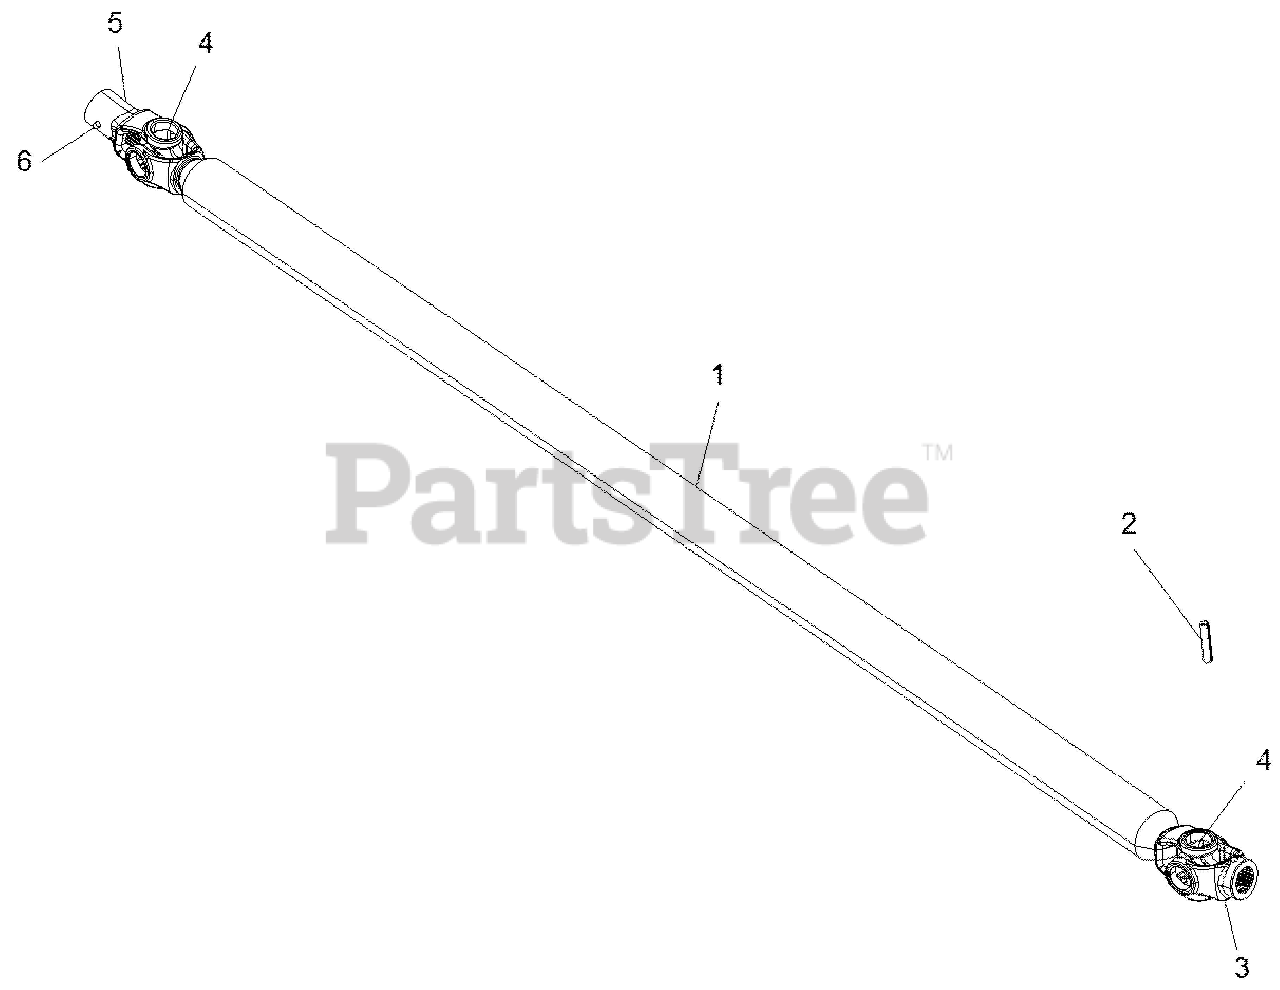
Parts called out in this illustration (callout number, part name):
1	ASM-PROPSHAFT,FRONT
2	PIN,SPRING(10)
4	KIT, CROSS & BEARING, NONGREASE
5	YOKE-SLIP (6272008)
6	FITTING, LUBRICATION
